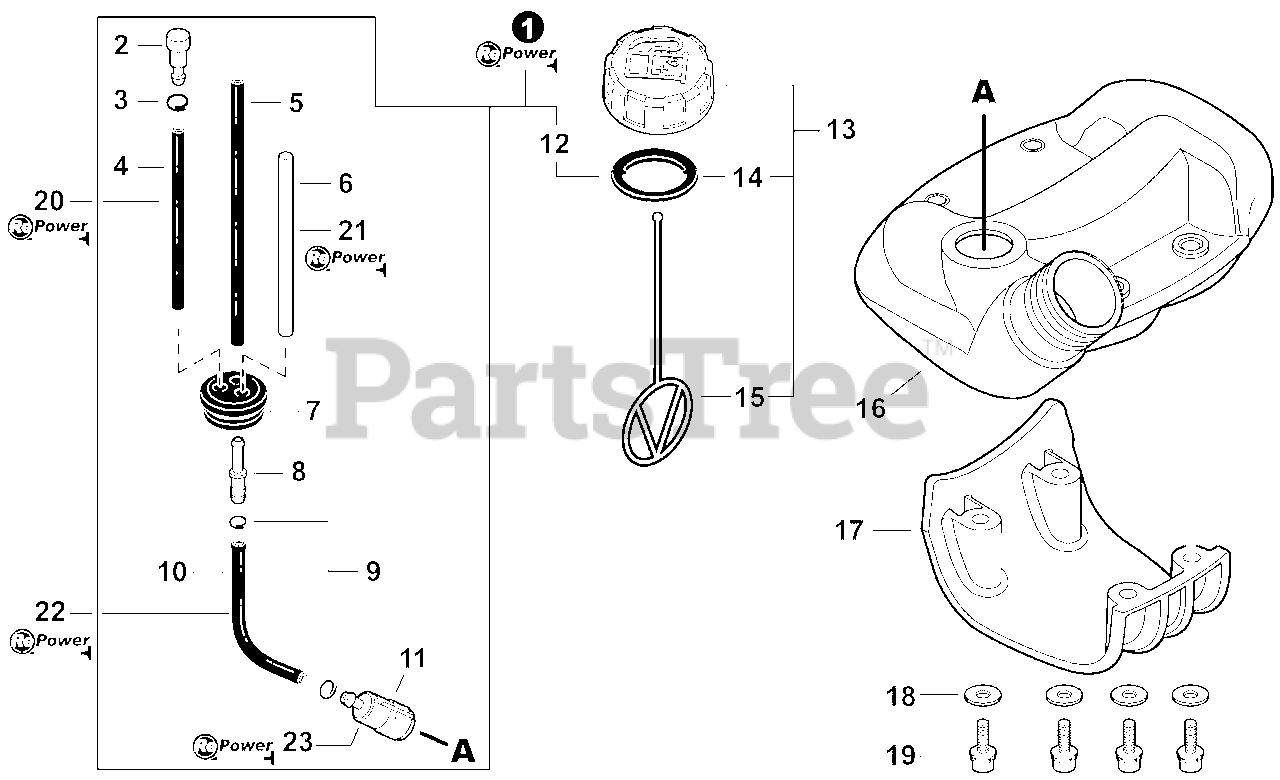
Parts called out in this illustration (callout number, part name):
1	FUEL SYSTEM KIT
2	VENT ASSY
3	CLIP Ø6.5 MM
4	PIPE, FUEL 3×6×35 BLACK
5	PIPE, FUEL - 3×5×67 - BLACK
6	PIPE, FUEL 3×6×75 CLEAR
7	GROMMET, FUEL
8	CONNECTOR, PIPE Ø5ר3.5
9	CLIP Ø6
10	PIPE, FUEL - 3×5×125 - BLACK
11	FILTER, FUEL 125-528
12	GASKET, FUEL CAP
13	CAP ASSY, FUEL
14	GASKET, FUEL CAP
15	CONNECTOR, CAP L= 100 MM
16	TANK, FUEL
17	GUARD, FUEL TANK
18	WASHER 5.5×12×0.8
19	BOLT 5×25
20	BULK PIPE - 3×6 MM BLACK (4 PIECES×2 M)
21	BULK PIPE - 3×6 MM CLEAR (4 PIECES×2 M)
22	BULK PIPE - 3×5 MM BLACK (4 PIECES×2 M)
23	TUNE-UP KIT - REPOWER
